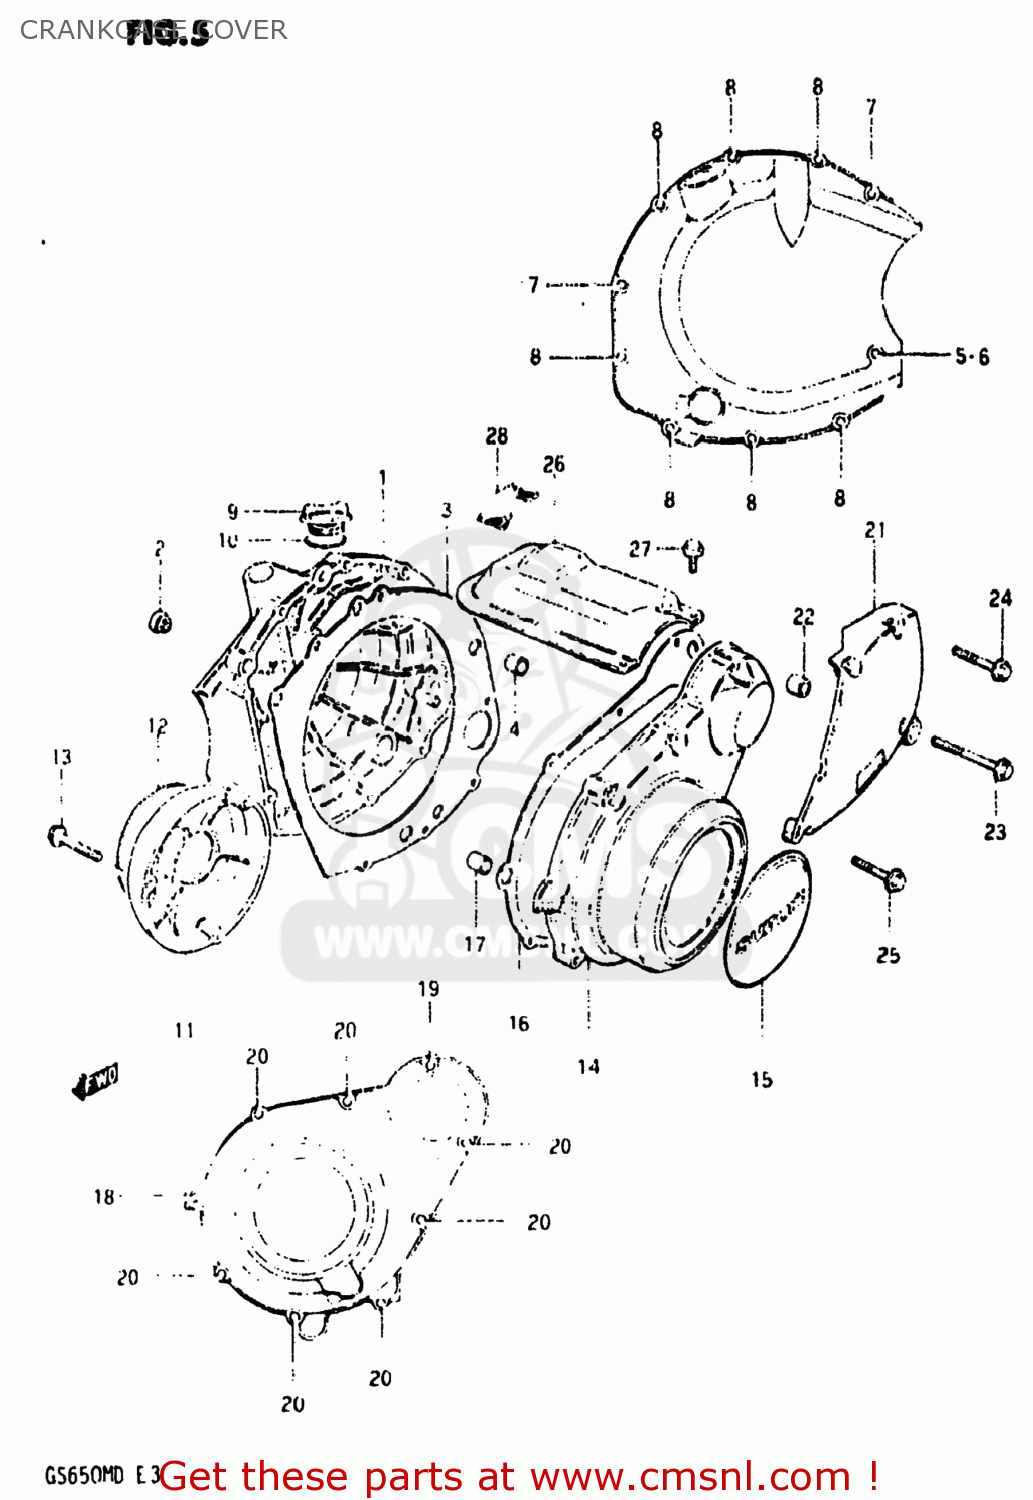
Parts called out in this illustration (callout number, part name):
1	COVER,CLUTCH
2	LENS,OIL LEVEL CHECK
3	GASKET,CLUTCH COVER (MCA)
4	PIN
5	GASKET (NAS)
6	BOLT (6X65)
7	BOLT (6X40)
8	BOLT (6*30)
9	PLUG
10	O-RING
11	COVER,CONTACT BREAKER
12	EMBLEM
13	BOLT (5X30)
14	COVER,MAGNETO
15	EMBLEM,MAGNETO COVER
16	GASKET,MAGNETO COVER (MCA)
17	PIN
18	BOLT (6X45)
19	BOLT (6X35)
20	BOLT (6*30)
21	COVER,SPROCKET
22	PIN
23	BOLT (6X40)
24	BOLT (6*30)
25	BOLT (6X25)
26	COVER,STARTER MOTOR
27	BOLT
28	DAMPER,STARTER MOTOR CLUTCH
